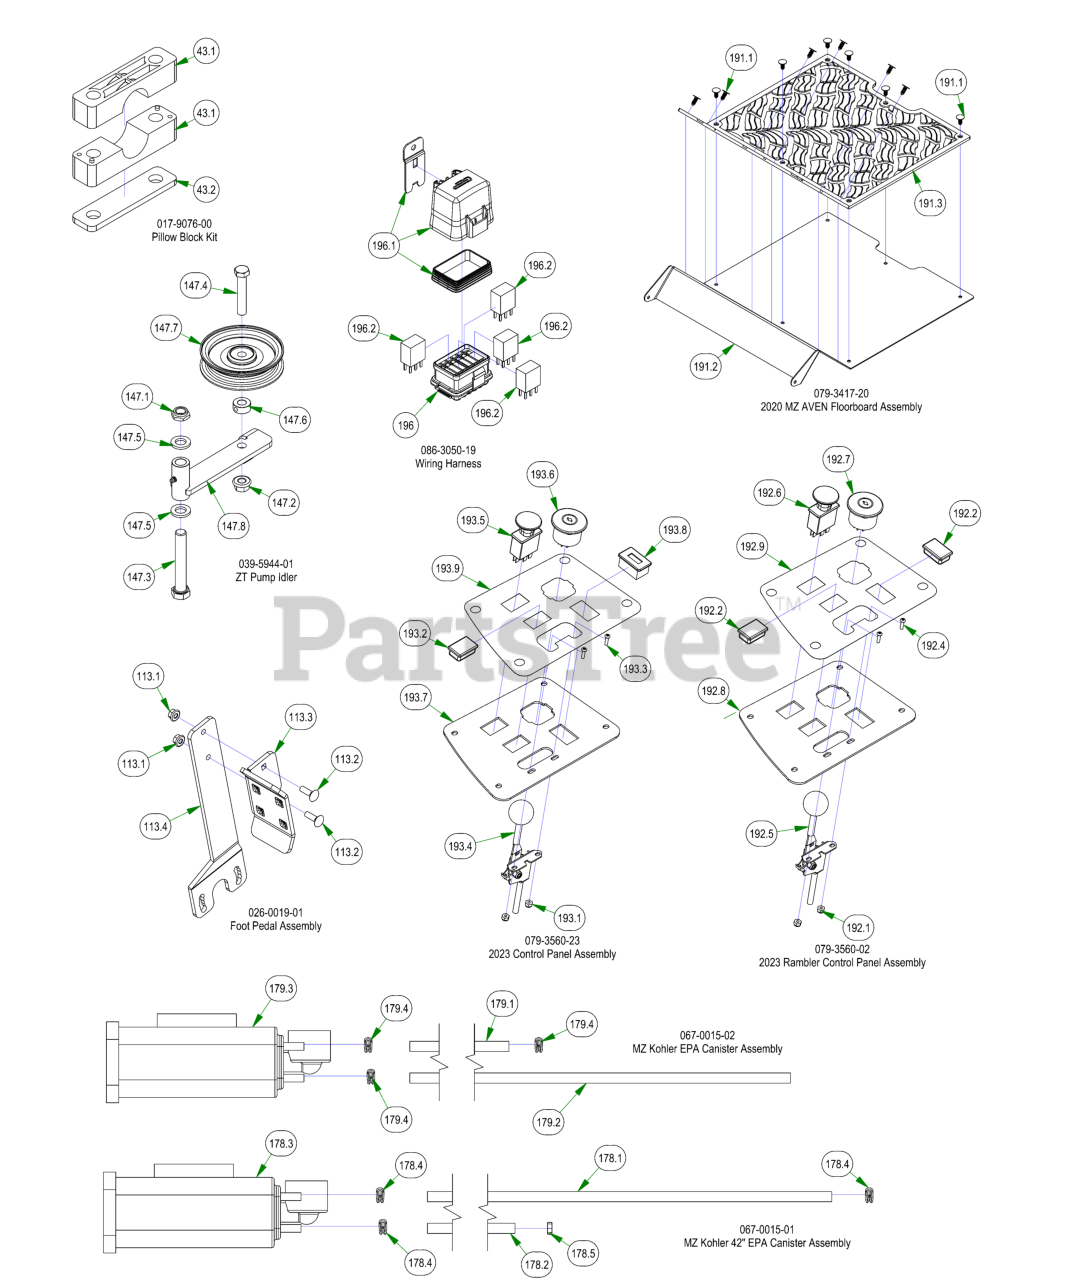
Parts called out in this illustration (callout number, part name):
43	Pillow Block Kit
43.1	Pillow Block MZ
43.2	Pillow Block Strap
113	Foot Pedal Assembly
113.1	5/16-18 NYLON INSERT FLANGE LOCKNUT ZINC
113.2	5/16-18 X 1 CARRIAGE BOLT (GR.8) ZINC
113.3	2017 MZ/ZT Shallow Foot Pedal
113.4	2017 MZ/ZT Deck Pedal Lever
147	ZT Pump Idler
147.1	5/8-11 NYLON INSERT JAM LOCKNUT ZINC
147.2	1/2-13 NYLON INSERT FLANGE LOCKNUT ZINC
147.3	5/8-11 X 4 HEX CAP SCREW (GR.8) ZINC YELLOW
147.4	1/2-13 X 2-3/4 HEX CAP SCREW (GR.5) ZINC
147.5	.635 ID X 1.120 OD X .140 THICK FLAT WASHER NYLON
147.6	1/2 SOLID SHAFT COLLAR (W/1 SET SCREW) ZINC
147.7	4 3/4" Idler Pulley
178	MZ Kohler 42" EPA Canister Assembly
178.1	3/16 Vinyl Tubing, 53"
178.2	3/16" Clear Vinyl Tubing, 44"
178.3	Carbon Canister for Magnum/MZ
178.4	8.6mm Hose Clamp
178.5	3/16" Vinyl Hose Clamp
179	MZ Kohler EPA Canister Assembly
179.1	3/16 Vinyl Tubing, 44"
179.2	3/16" Clear Vinyl Tubing, 52"
179.3	Carbon Canister for Magnum/MZ
179.4	8.6mm Hose Clamp
191	2020 MZ AVEN Floorboard Assembly
191.1	Ratchet Fastener
191.2	MZ/ZT 2017 Floorboard
191.3	2021 Maverick Floor Mat W/ Reaper Tread
192	2023 Rambler Control Panel Assembly
192.1	10-24 Nylon Insert Locknut Zinc Orange Nylon
192.2	Light Plug
192.4	10-24 X 5/8 BS Button Head Bolt
192.5	Throttle Lever Assembly
192.6	PTO Engager
192.7	Ignition Switch
192.8	2022 Maverick HD control panel
192.9	2023 MZ/Magnum/ZT/Maverick Control Panel Decal
193	2023 Control Panel Assembly
193.1	10-24 Nylon Insert Locknut Zinc Orange Nylon
193.2	Light Plug
193.3	10-24 X 5/8 BS Button Head Bolt
193.4	Throttle Lever Assembly
193.5	PTO Engager
193.6	Ignition Switch
193.7	2022 Maverick HD control panel
193.8	Tachometer
193.9	2023 MZ/Magnum/ZT/Maverick Control Panel Decal
196	Wiring Harness
196.1	Relay Block Cover Replacement Kit
